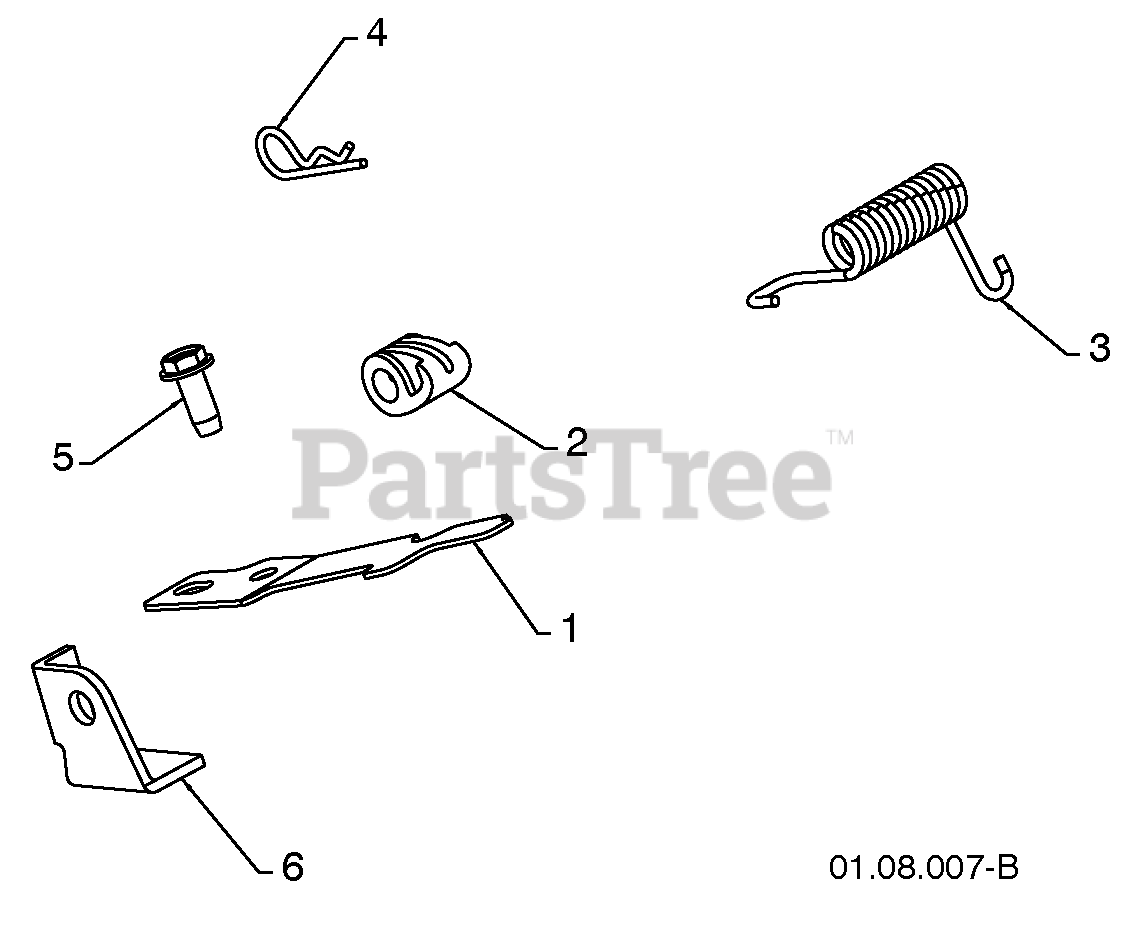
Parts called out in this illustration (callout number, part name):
1	INTERLOCK SPRING
2	INTERLOCK CAM
3	TORSION SPRING
4	RETAINER
5	SCREW 1/4-20 X .625
6	INTERLOCK STOP
